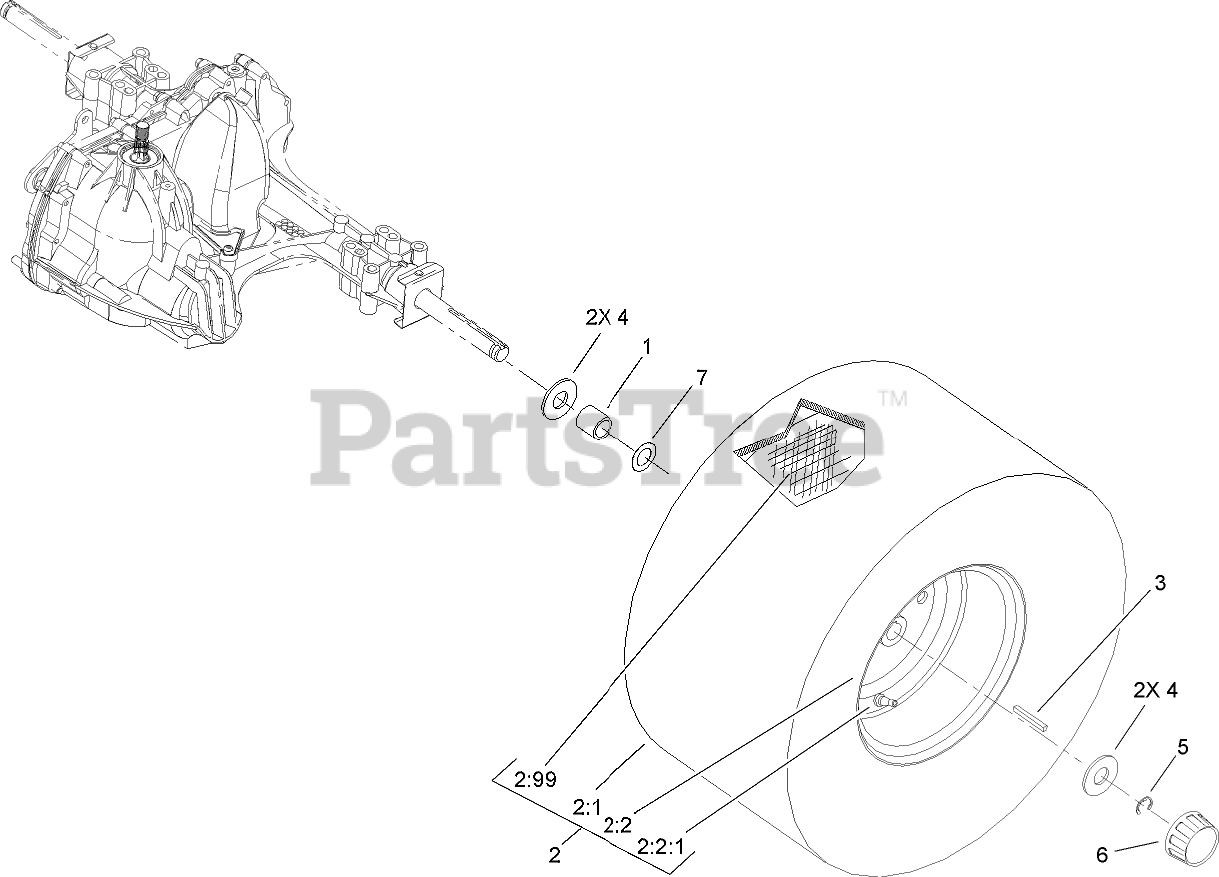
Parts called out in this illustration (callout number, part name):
1	SPACER-WHEEL
2	REAR WHEEL & TIRE ASM
2:2:1	STEM-VALVE
2:99	TUBE-INNER
3	KEY-SQUARE
4	WASHER-PLAIN
5	E-RING
6	CAP-HUB
7	WASHER-THRUST
